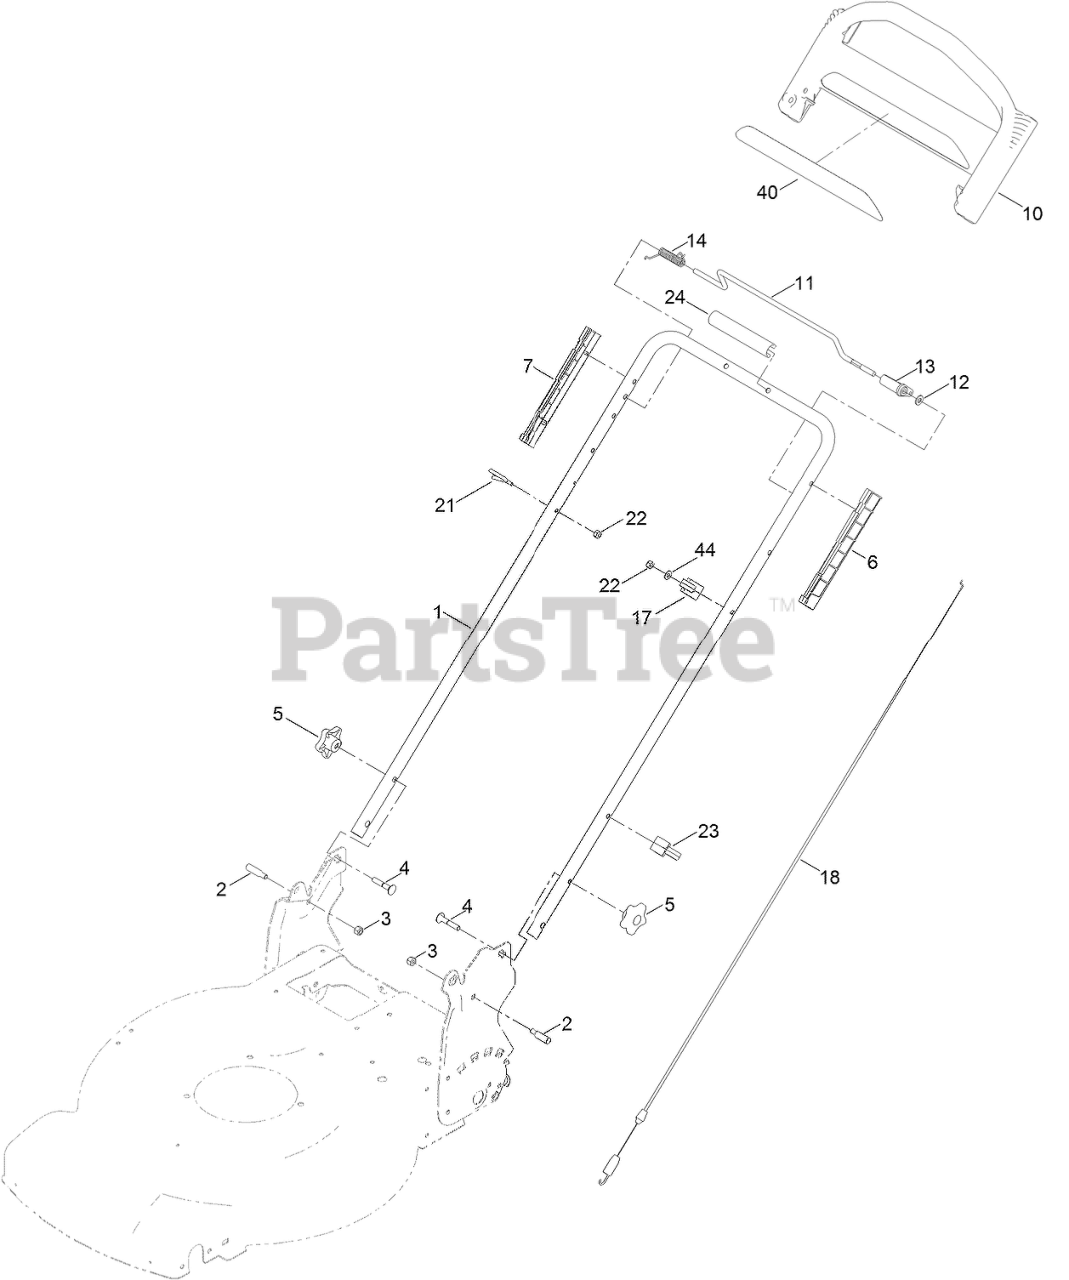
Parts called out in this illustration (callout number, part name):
2	BOLT-SHOULDER
3	NUT-LOCK, NI
4	SCREW-CARR
5	KNOB-HANDLE
6	GUIDE-LH
7	GUIDE-RH
10	HANDLE-CONTROL
11	BAR-CONTROL, TRACTION
12	WASHER-PLAIN
13	LEVER-TRACTION
14	SPRING-TORSION
17	ANCHOR-CABLE
18	CABLE-TRACTION
21	GUIDE-ROPE
22	NUT-LOCK, NI
23	GUIDE-CABLE
24	HANDLE-COVER
44	WASHER-FLAT
